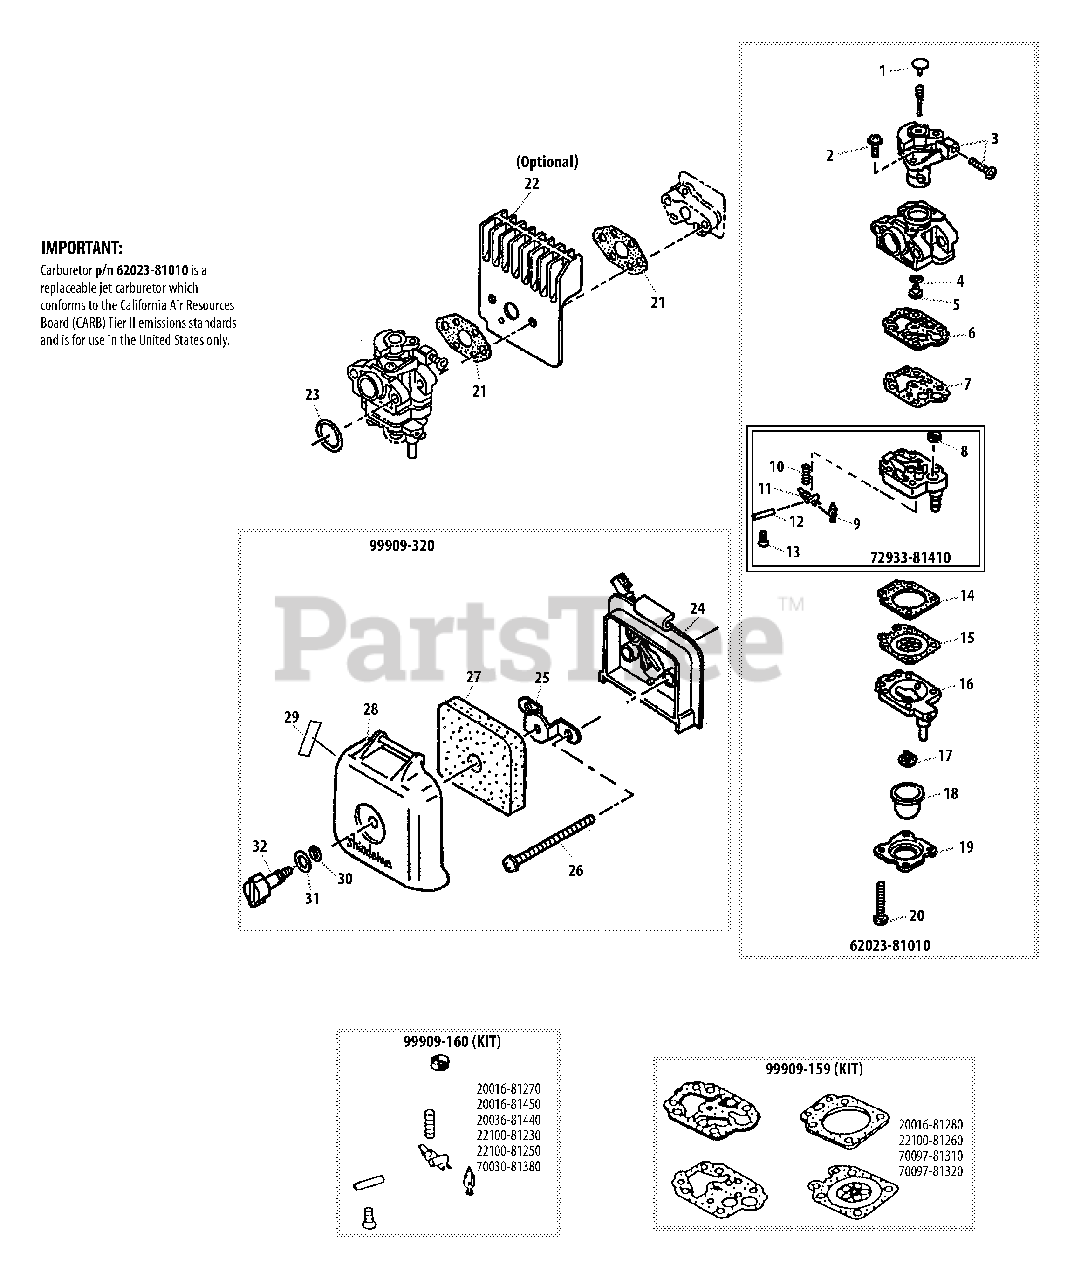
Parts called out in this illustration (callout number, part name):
1	PLUG
2	SCREW, THROTTLE COLLAR
3	THROTTLE VALVE ASSY
4	O-RING
5	JET, MAIN
6	GASKET, PUMP
7	DIAPHRAGM, PUMP
8	SCREEN, FUEL INLET
9	VALVE, INLET NEEDLE
10	SPRING, METERING LEVER
11	LEVER, METERING
12	PIN, METERING LEVER
13	SCREW
14	GASKET, METERING DIAPHRAGM
15	DIAPHRAGM, METERING
16	BODY ASSY, PURGE
17	VALVE, CHECK
18	BULB, PURGE
19	RETAINER, PURGE BULB
20	SCREW
21	GASKET, CARBURETOR
22	DEFLECTOR, HEAT
23	O-RING 15
24	CASE, AIR FILTER
25	BRACKET
26	SCREW - 5×67
27	FILTER, AIR
28	COVER, AIR FILTER
29	LABEL, CHOKE
30	O-RING
31	WASHER, CONE M6
32	THUMBSCREW
62023-81010	CARBURETOR
72933-81410	BODY ASSY, PUMP
99909-159	GASKET / DIAPHRAGM KIT
99909-160	VALVE KIT, INLET NEEDLE
99909-320	AIR FILTER ASSY
